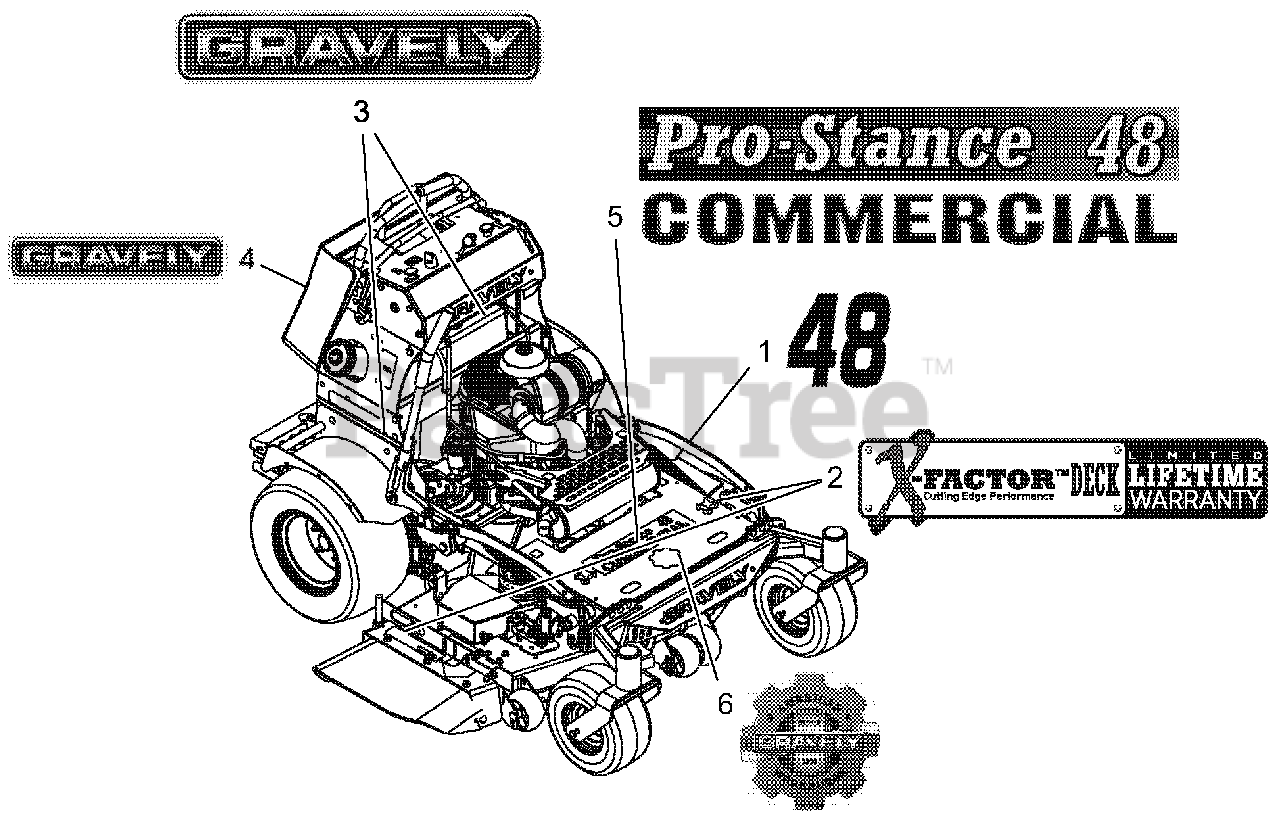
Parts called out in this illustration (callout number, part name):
1	DECAL, 48"
2	DECAL, X-FACTOR DECK
3	DECAL, 9.5" GRAVELY LOGO
4	DECAL, FUEL TANK-GRAVELY
5	DECAL, PROSTANCE 48"
6	DECAL, GRAVELY HERITAGE-LARGE
